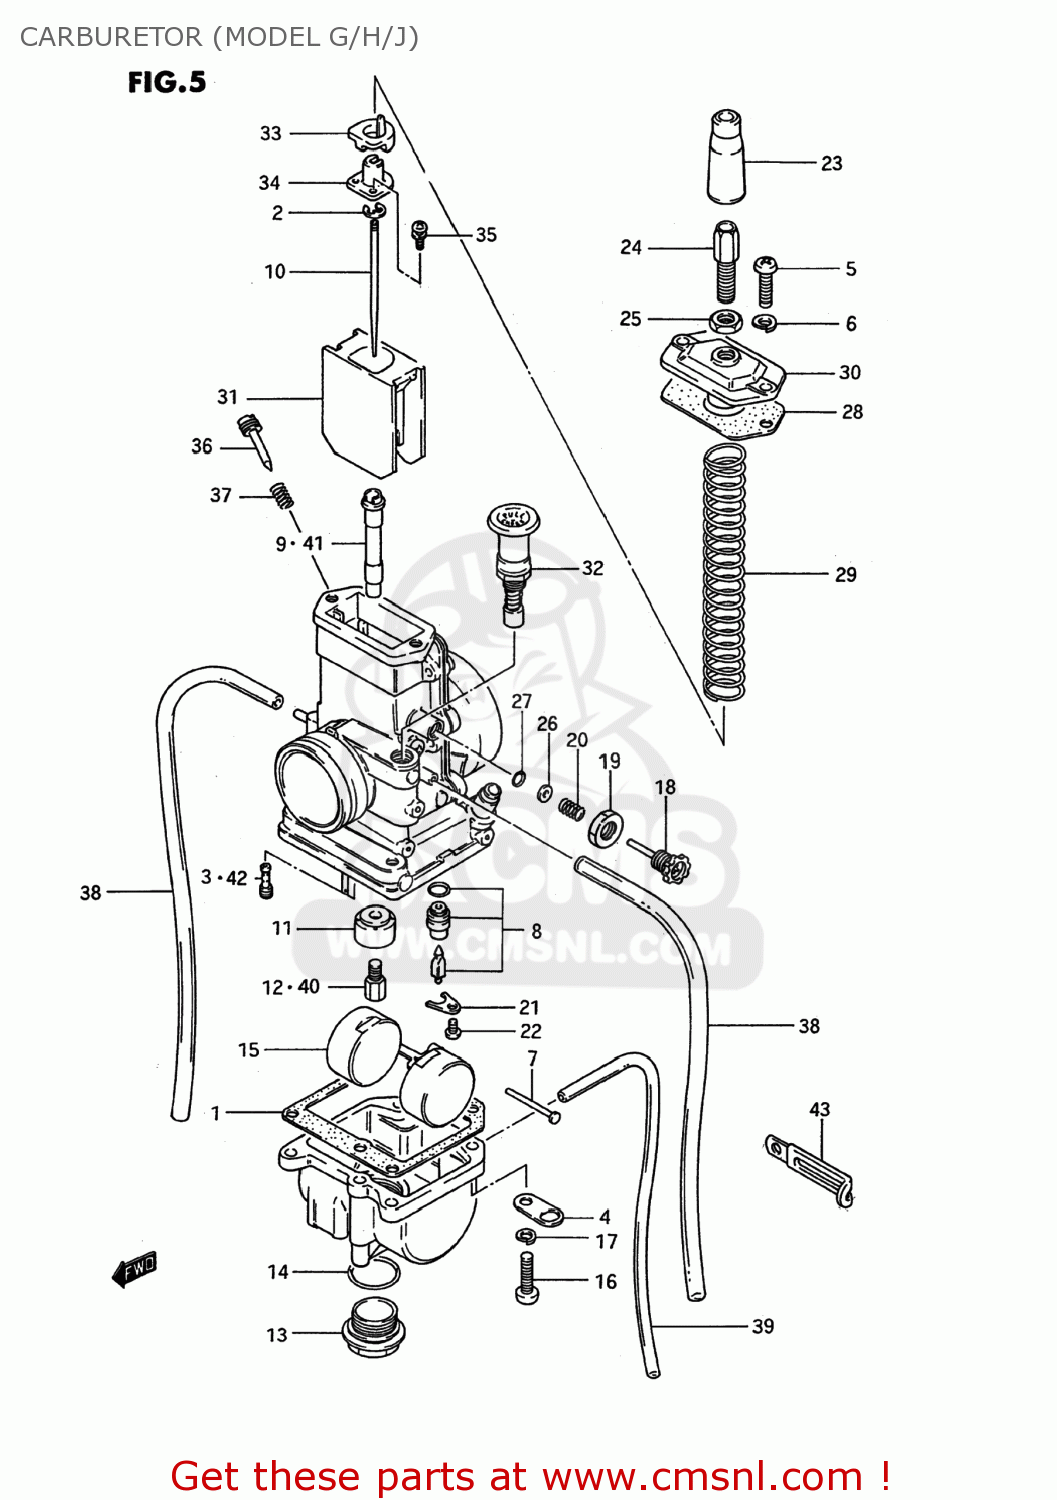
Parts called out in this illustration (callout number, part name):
1	GASKET,FLOAT CHAMBER (NAS)
2	CLIP
3	JET,PILOT(30)
4	PLATE,CARBURETOR
5	SCREW
6	LOCK WASHER
7	PIN,FLOAT
8	VALVE ASSY,NEEDLE
9	JET,NEEDLE,P-2
10	NEEDLE,JET(5DP39-4)
11	RING
12	JET,MAIN(180)
13	PLUG
14	O RING
15	FLOAT
16	SCREW
17	LOCK WASHER
18	ADJUSTER,THROTTLE STOP
19	NUT
20	SPRING
21	PLATE
22	SCREW
23	CAP,CABLE ADJUSTER
24	ADJUSTER,CABLE
25	NUT
26	WASHER
27	O RING
28	GASKET,CARBURETOR TOP (NAS)
29	SPRING
30	CAP,CARBURETOR TOP
31	VALVE,THROTTLE
32	VALVE ASSEMBLY,STARTER
33	RING
34	JOINT
35	SCREW
36	SCREW,AIR
37	SPRING
38	HOSE
39	HOSE
40	JET
41	JET,NEEDLE
42	JET,PILOT(25)
43	CLAMP L:35
